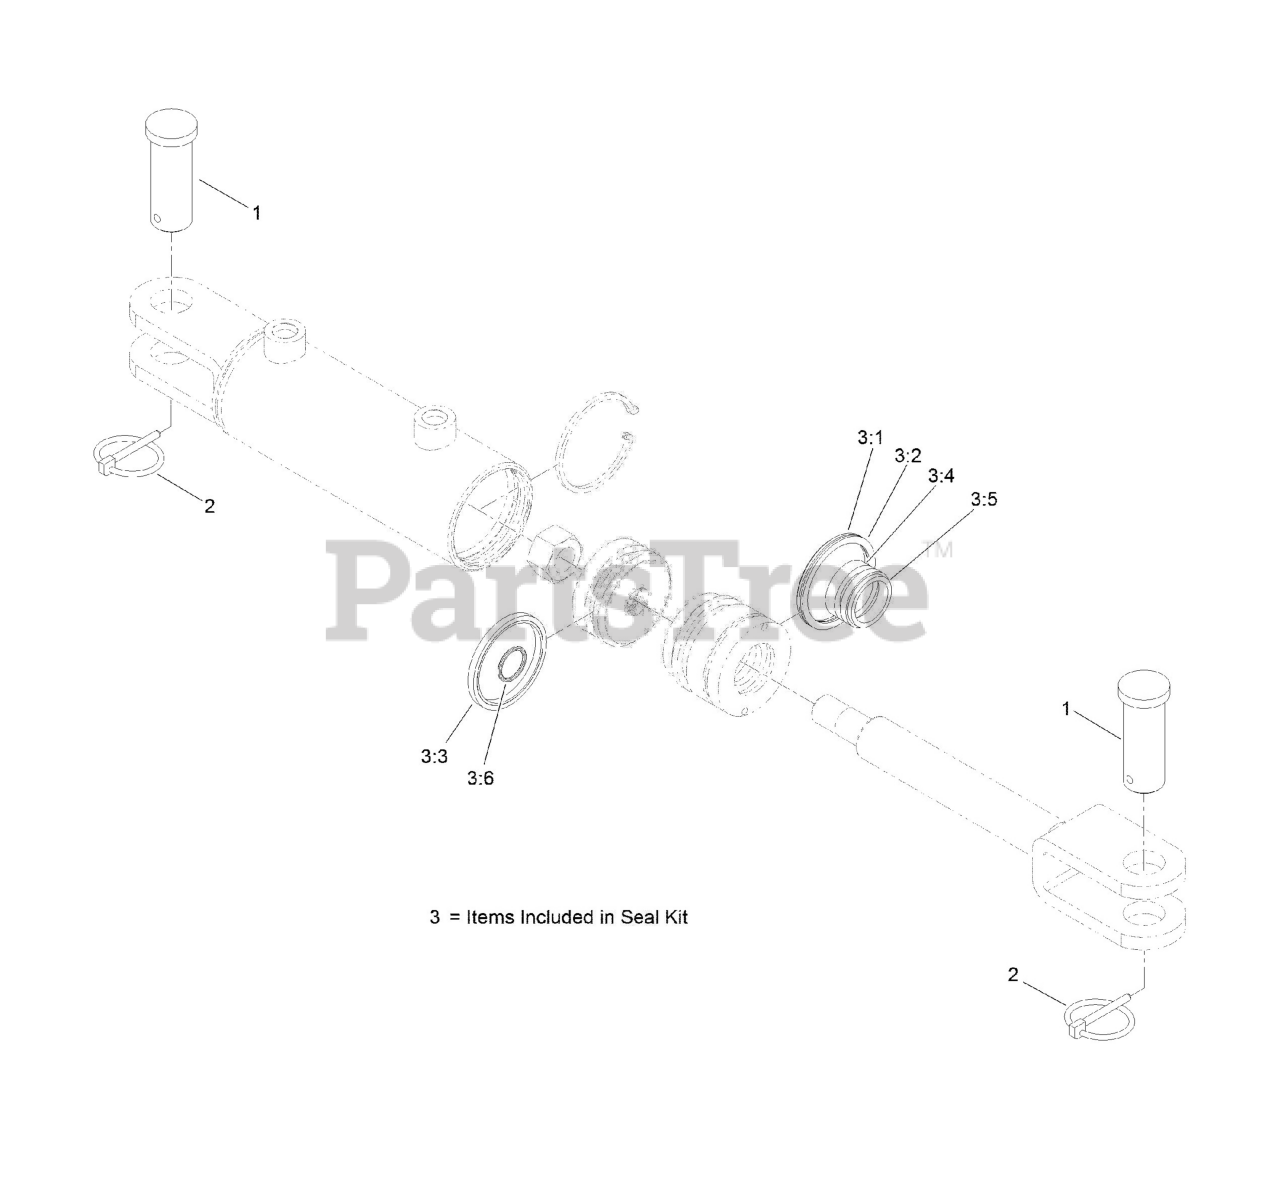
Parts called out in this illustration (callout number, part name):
1	PIN-CLEVIS
2	PIN-LYNCH
3:1	O-Ring
3:2	Backup Ring
3:3	Psp Seal
3:4	Bs Seal
3:5	Dust Seal
3:6	O-Ring
